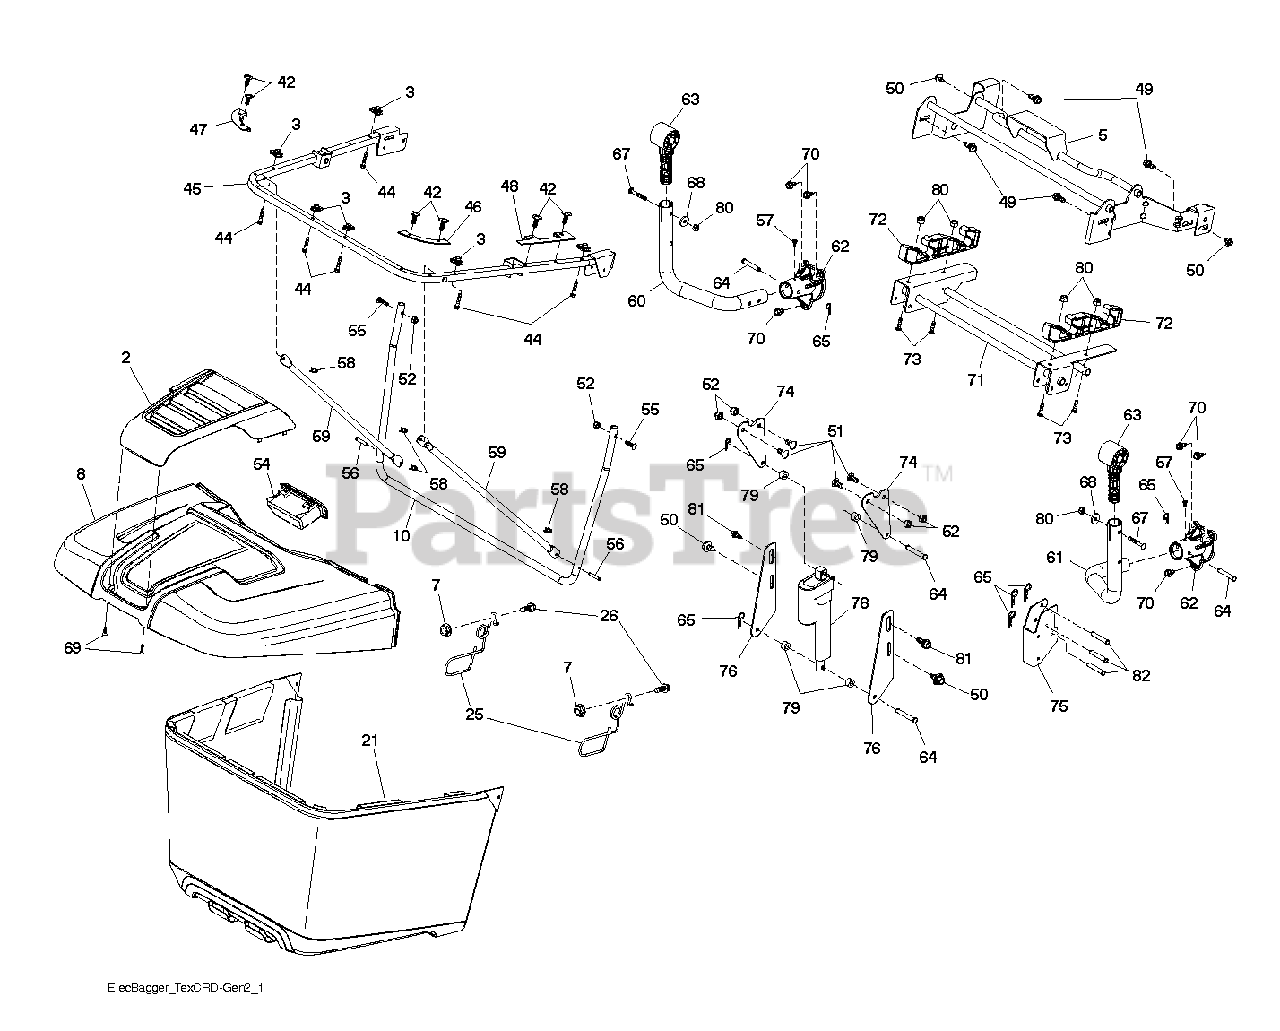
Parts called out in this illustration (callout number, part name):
2	APPLIQUE.BAGGER
3	1/4-20 U NUT
5	SCREW.PAN.HEAD
7	NUT T
10	FRAME TEX_CRD_GEN2 BAGGER FRAM
21	BAG FRAME BAGGER ASSEMBLY. HUS
25	LATCH LATCH. BAG. CRD GEN 2
26	SCREW HEX CRT
42	CLIP CHRISTMAS TREE CLIP
45	FRAME TEX_CRD_GEN2 UPPER U FRA
46	CONNECTOR LEFT BAGGER CORNER C
47	CONNECTOR RIGHT BAGGER CORNER
48	BAFFLE BAGGER SIDE CLOSE-OUT
49	BOLT, SHOULDER 5/16-18
50	BOLT, 5/16-18 X 1 3/4
51	BOLT.CARR.SQNK.5/16-18UNC.X3/4
52	NUT.71038.31-18.HEX.NYLOCK
54	HANDLE BAGGER TOP FRONT HANDLE
55	BOLT
56	PIN.CLEVIS.183
57	SCREW T-30 1/4-20 X
58	RETAINER CLIP PM
59	TUBE BAGGER SPREADER TUBE, TEX
63	BAGGER.PIVOT.ELECT.DUMP.TEXCRD
65	RETAINER M
69	SCREW,#8.FLAT.HEAD.DRILL.TIP
70	SCREW, 3/8-16X3/4
73	BOLT.CARRIAGE.5/16-18
79	SPACER.NYLON.75" X .4375
80	NUT LOCK HEX FLANGE 5/16-18
81	SHOULDER BOLT 5/16-18TT
